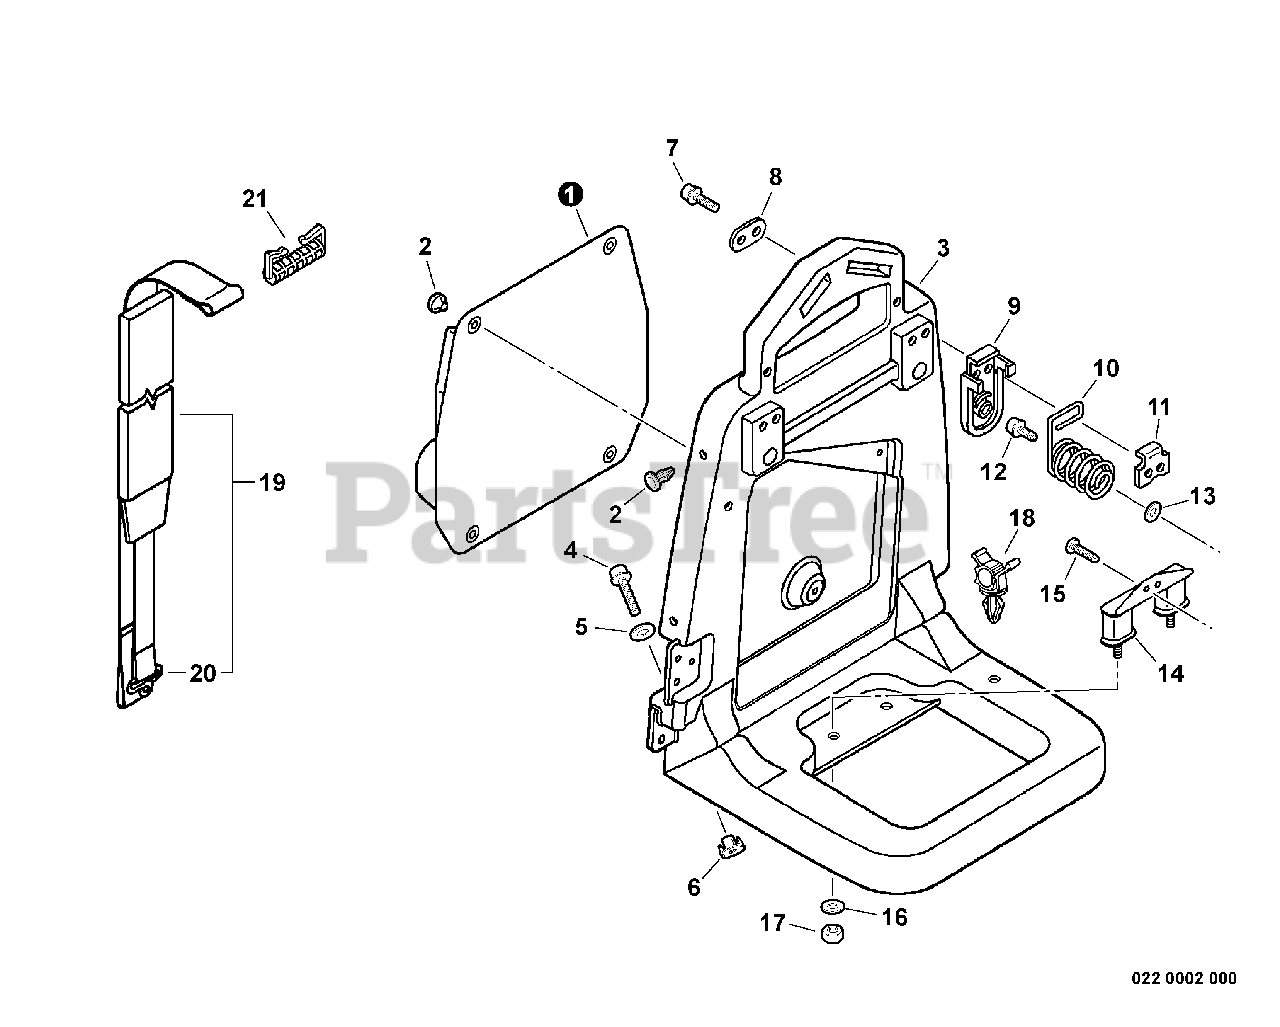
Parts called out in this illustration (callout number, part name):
1	CUSHION, BACKPACK
3	FRAME, BACKPACK
4	SCREW - 6X25
5	WASHER - 6
7	SCREW - 5X20
9	BRACKET, SPRING
11	RETAINER
12	SCREW - 5X20
13	WASHER - 5
14	CUSHION
15	SCREW - 5X16 -- TAPPING
17	NUT - 5 -- FLANGE
18	CLIP, CABLE
19	BACKPACK STRAP ASSY
21	RETAINER, HARNESS
